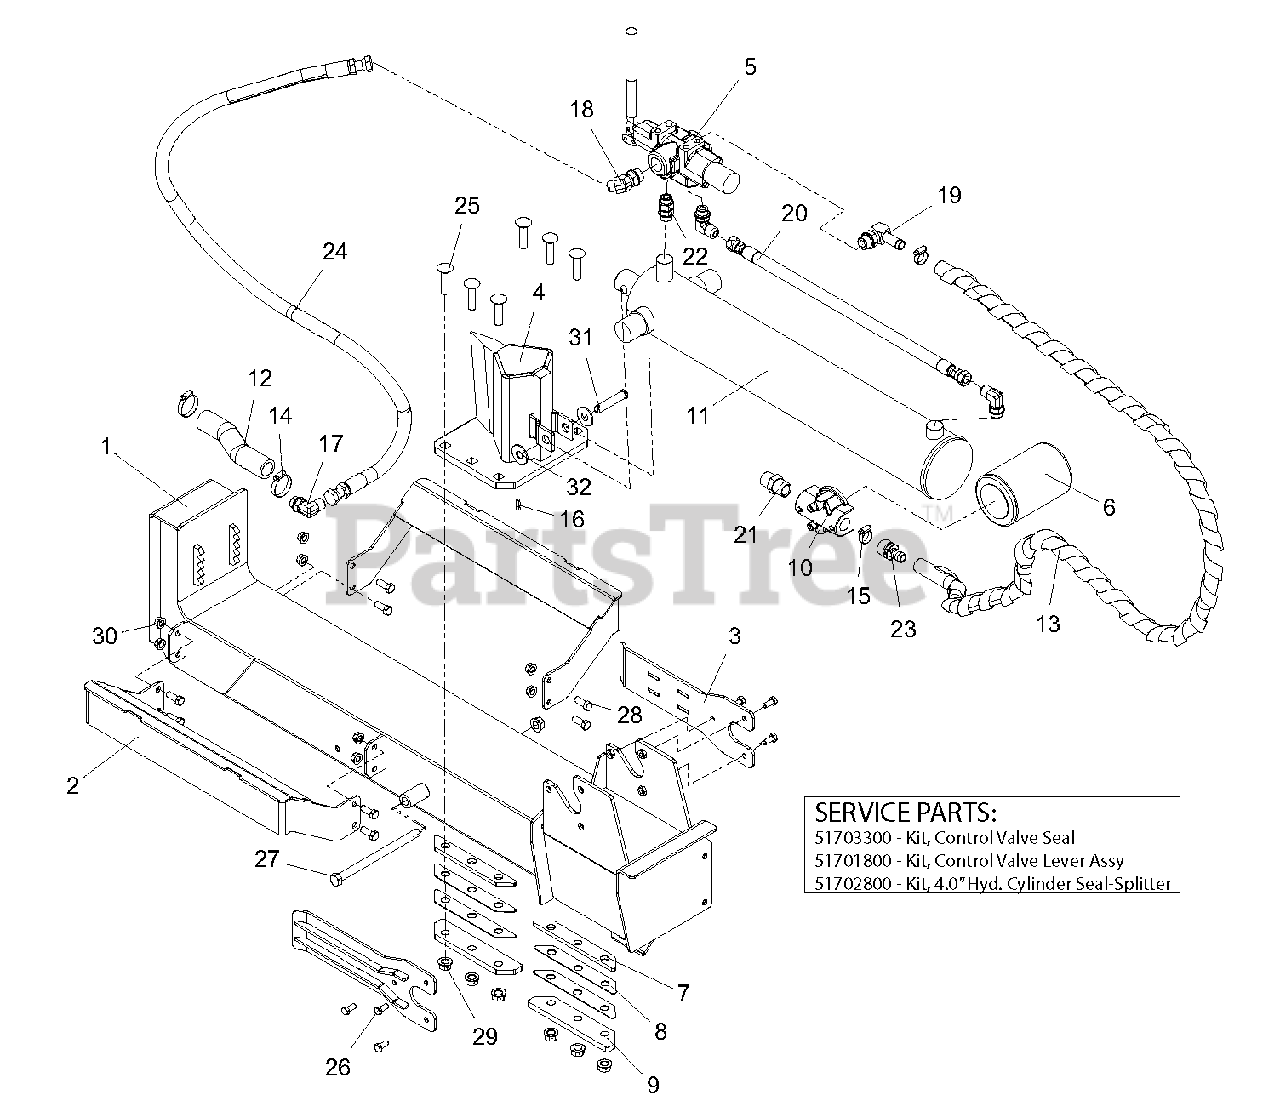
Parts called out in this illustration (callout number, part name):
1	WLDMT, BEAM - 22 TON SPLITTER
2	WLDMT, CRADLE, LOG SPLITTER
3	PLATE, STRIPPER
4	WLDMT, SPLITTER WEDGE
5	VALVE CONTROL-SPLITTER
5	KIT,CONTROL VALVE SEAL
5	KIT,CONTROL VALVE LEVER ASSY
6	FILTER,OIL-W/BYPASS
7	SPACER, WEDGE
8	SHIM,SPLITTER WEDGE
9	RETAINER,WEDGE
10	HEAD,FILTER-3/4 NPT BYPASS
11	CYLINDER, SPLITTER 4.0
11	KIT,4.0" HYD CYL SEAL-SPLITTER
12	HOSE, HYD - SUCTION 7.375"
13	HOSE, HYD-RET 801-10 WP 74"
14	CLAMP-HOSE 1.50X.81X1.42
15	CLAMP,.88 DIA. HOSE
16	CLIP, SPRING
17	FTG,HYD 6801-8-8
18	FTG,HYD 6802-8-10
19	FTG,HYD 4601-10-10
20	HOSE, HYD - 22"
21	FTG,HYD 5404-12-12
22	FTG, HYD - STR 08MAORB-08MORB
23	FTG,HYD STRAIGHT 10-12
24	HOSE, HYD - 58"
25	BLT-RDHDSQNKFTH.50-13X2 G8YWZC
26	@BLT-HEX .31-18X.75 GR5 YWZC
27	@BLT-HEX .50-13X7.50 GR5 YWZC
28	@BLT-HEX .38-16X1.00 GR5 YWZC
29	NUT-LK-CTR-FLG .50-13 YWZC
30	@NUT-LK-TOP-FLG .38-16 YWZC
31	PIN-CLEV .50X2.50X2.27 YWZC
32	@WSHR-FL-STL.563X1.38X.109YWZC
